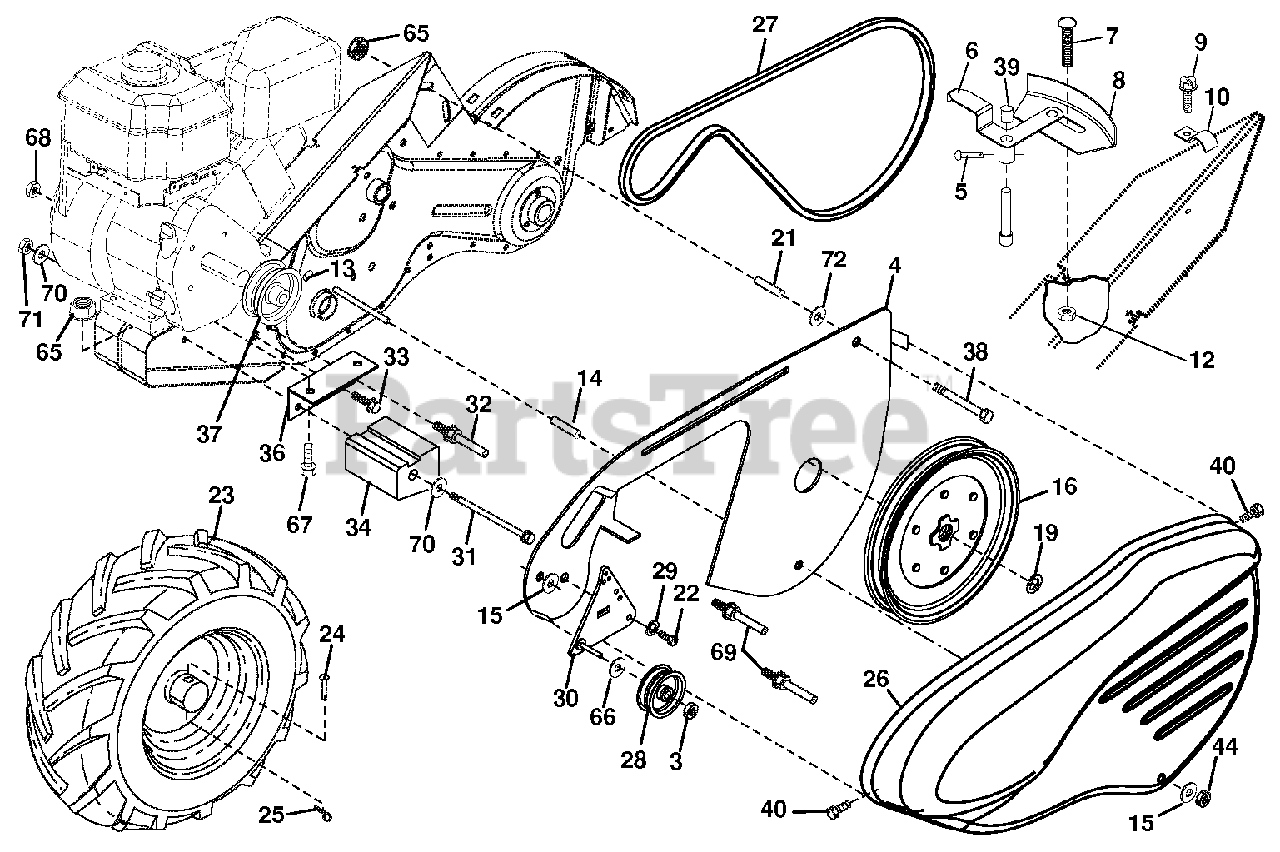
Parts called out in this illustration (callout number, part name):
3	NUT.CENTERLOCK.3/8-16 UNC.
4	SHIELD, INNER BELT GUARD
5	Pin, Shift Lever
6	Lever, Shift
7	Bolt 1/4-20 unc x 1/2 Gr. 5
8	Plate, Shift Indicator
9	Screw, Tap Hex Head
10	Clip, Cable
12	Nut, Keps Hex 1/4-20 unc
13	Screw Set 5/16-18 x 3/8 Patch
14	Spacer, Split .327 x .42 x 1.2
15	Washer 11/32 x 11/16 x 16 Ga.
16	Sheave, Transmission
19	Ring, Retainer
21	Spacer, Split .327 x .42 x 1.2
22	Bolt, Hex Head 5/16-24 unf x 1
23	TIRE AND WHEEL ASSEMBLY
24	Rivet, Drilled
25	Retainer Spring
26	GUARD, BELT
27	Belt, V
28	Pulley, Idler
29	Ring, Klip
30	BRACKET, IDLER
31	BOLT, HEX HEAD 5/16-16 X 12
32	Shaft, Idler Arm
33	Bolt, Hex 3/8-16 x 1
34	COUNTERWEIGHT, LH
36	Bracket, Reinforcement, LH
37	Sheave, Engine
38	Bolt, Fin Hex 5/16-18 x 2-3/4
39	Cap, Plunger
40	Screw Hex Wsh Hd #8-18 x 1/2
44	Locknut, Washer Insert 5/16-18
65	Nut, Hex, Flangelock
66	Washer 13/32 x 13/16 x 12 Ga.
67	Bolt, Fin Hex 5/16-18 unc x 1-
68	Nut Keps Hex 3/8-16 unc
69	KEEPER BELT ENGINE
70	WASHER.13/32 X 1-1/4 X 12 GA.
71	Nut, Hex, Crownlock 3/8-16
72	COUNTERWEIGHT, LH
